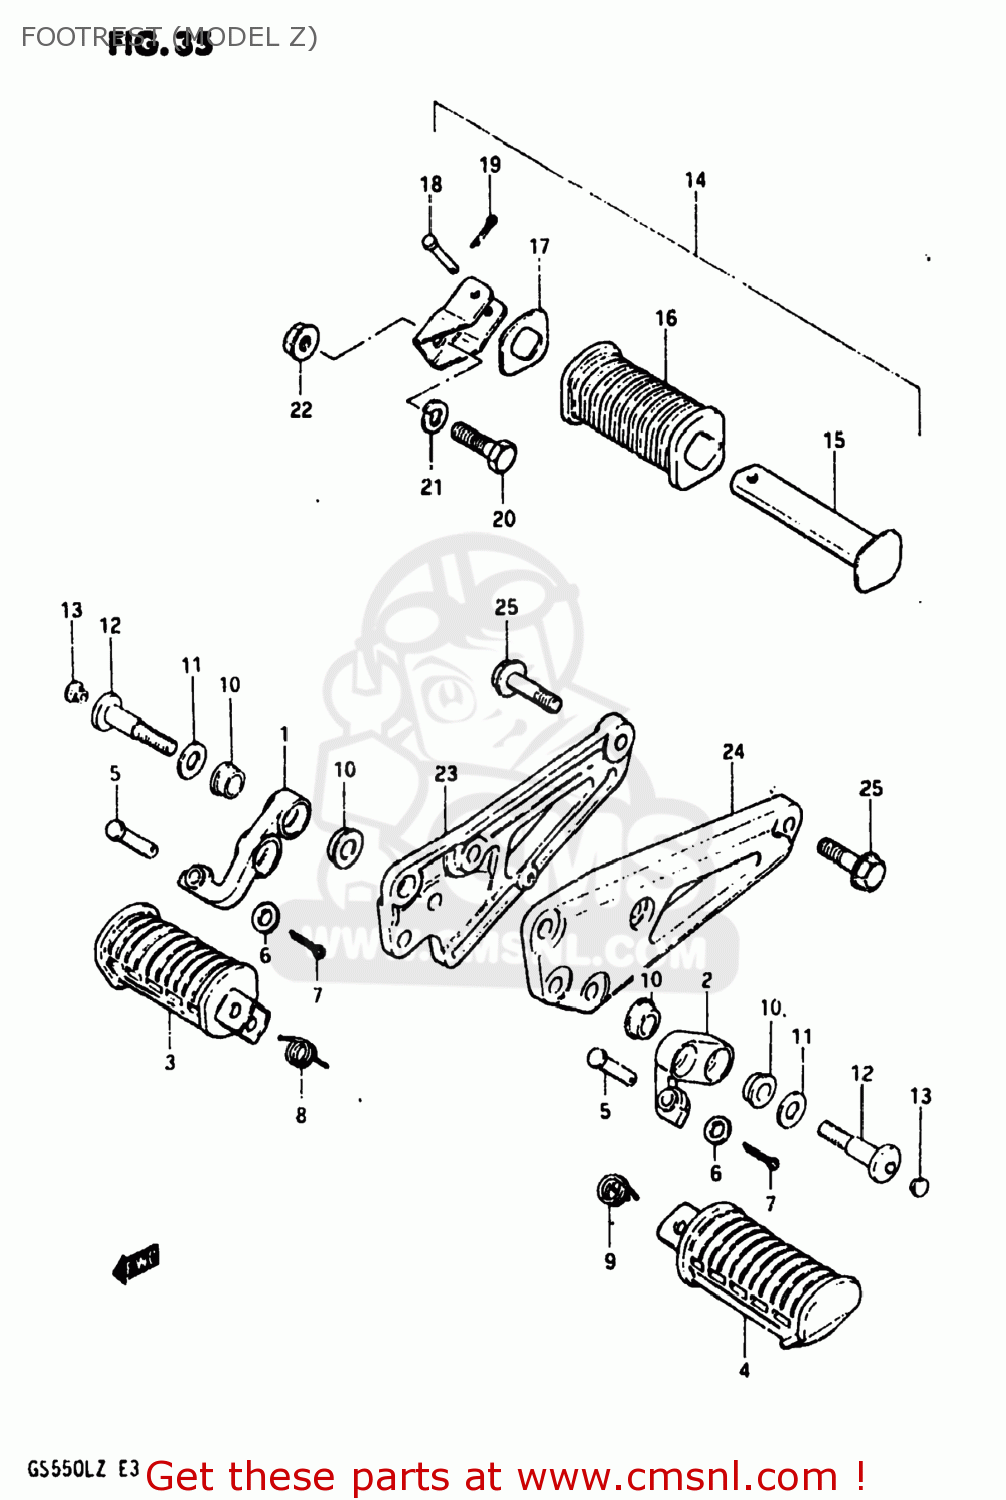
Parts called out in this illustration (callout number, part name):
1	BAR,FRONT FOOTREST,RIGHT
2	BAR,FRONT FOOTREST,LEFT
3	RUBBER,FOOTREST
4	FOOTREST
5	PIN
6	WASHER
7	PIN
8	SPRING
9	SPRING
10	BUSH
11	WASHER(10.5X28X2.3)
12	BOLT
13	CAP
14	FOOTREST ASSY,PILLION,R
15	BAR,REAR FOOTREST,LEFT
16	RUBBER,PILLION FOOTREST
17	WASHER,FOOTREST RUBBER
18	PIN
19	PIN
20	BOLT,M10X1.25X
21	LOCK WASHER
22	NUT
23	BRACKET
24	BRACKET,MUFFLER,LEFT
25	BOLT
